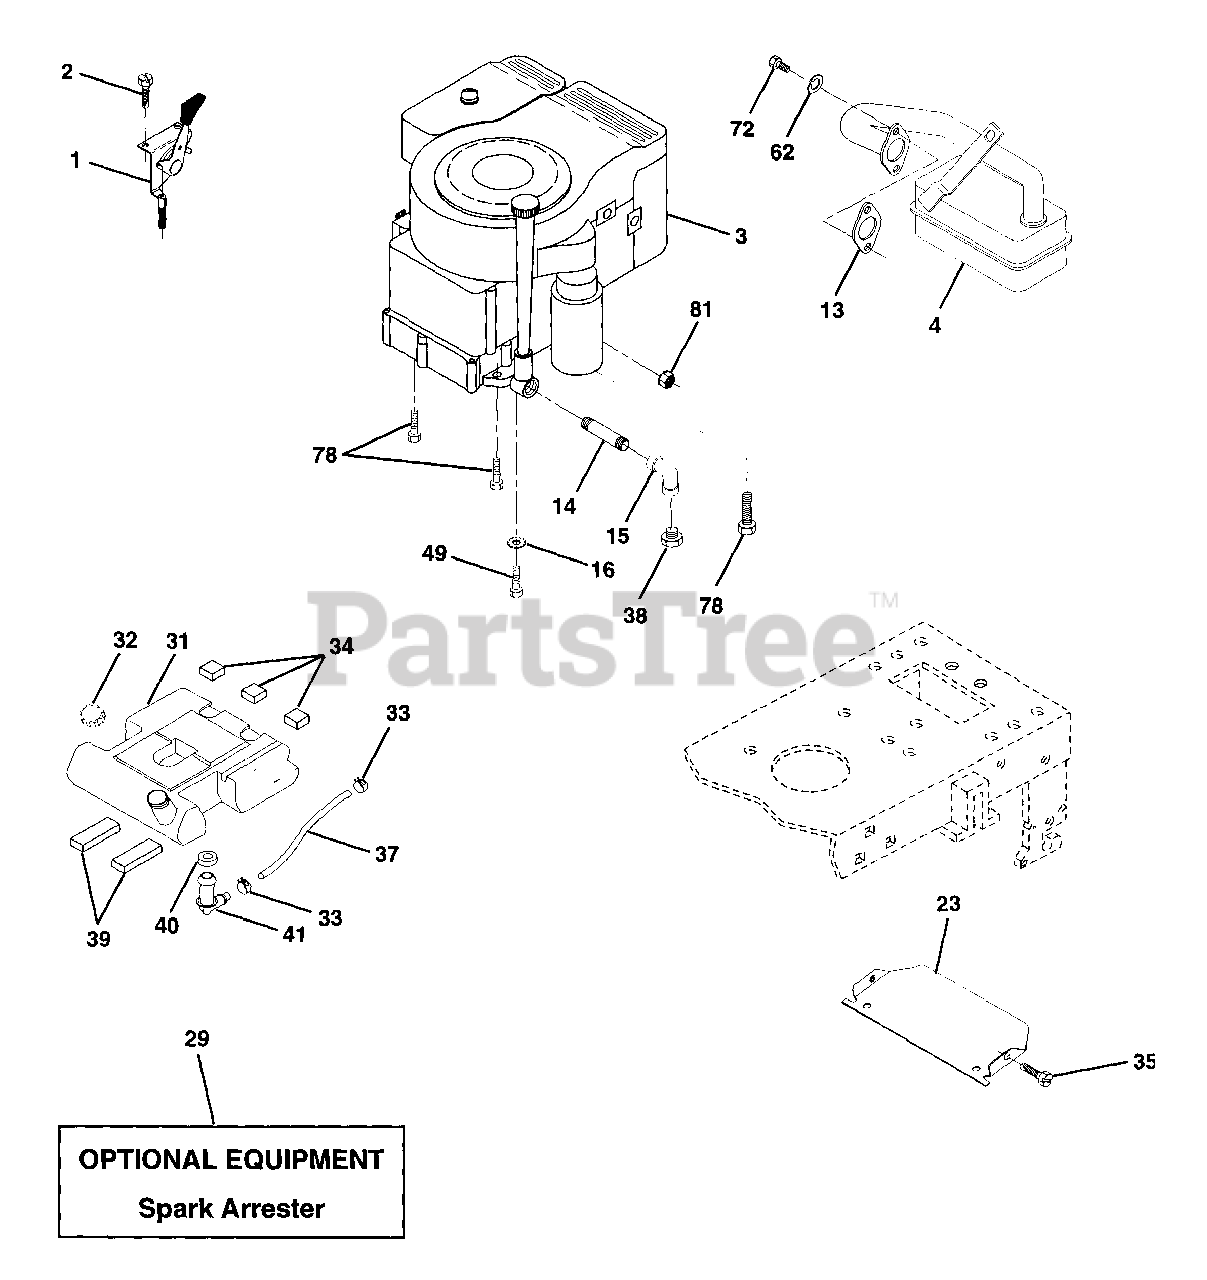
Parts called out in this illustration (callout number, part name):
1	Control Th/ch 23 5 LH Flag
2	Screw Hex Thd Cut 1/4-20 x 5/8 T
4	Muffler LT B & S Exhaust
13	Gasket Eng 1 313 Id Tin Plated
14	Nipple Pipe 3/8 Npt X 3"
15	Elbow Std 90 Degree 3/8-18 Npt
16	Washer Lock Ext Tooth 3/8
23	Shield Heat
29	Kit Spark Arrestor (Flat Scrn)
31	Tank Fuel
32	Cap Asm Fuel W/sym Vented
33	Clamp Hose Black
34	Pad Spacer 1 x 1 x 1 Blk
35	Screw
37	Line Fuel 7.5"
38	Plug Oil Drain (Order From Engine Manufacturer)
39	Pad Spacer 1.75 x .75 x .06
40	Bushing
41	Stem Tank Fuel
49	Screw
62	Washer Lock Hvy Hlcl Spr 5/16
72	Screw Hexhd Cap 5/16-18 x 3/4
78	Screw Thdrol 3/8-16 x 1-1/4 TYTT
81	Nut Flange 1/4-20 Starter Nut
